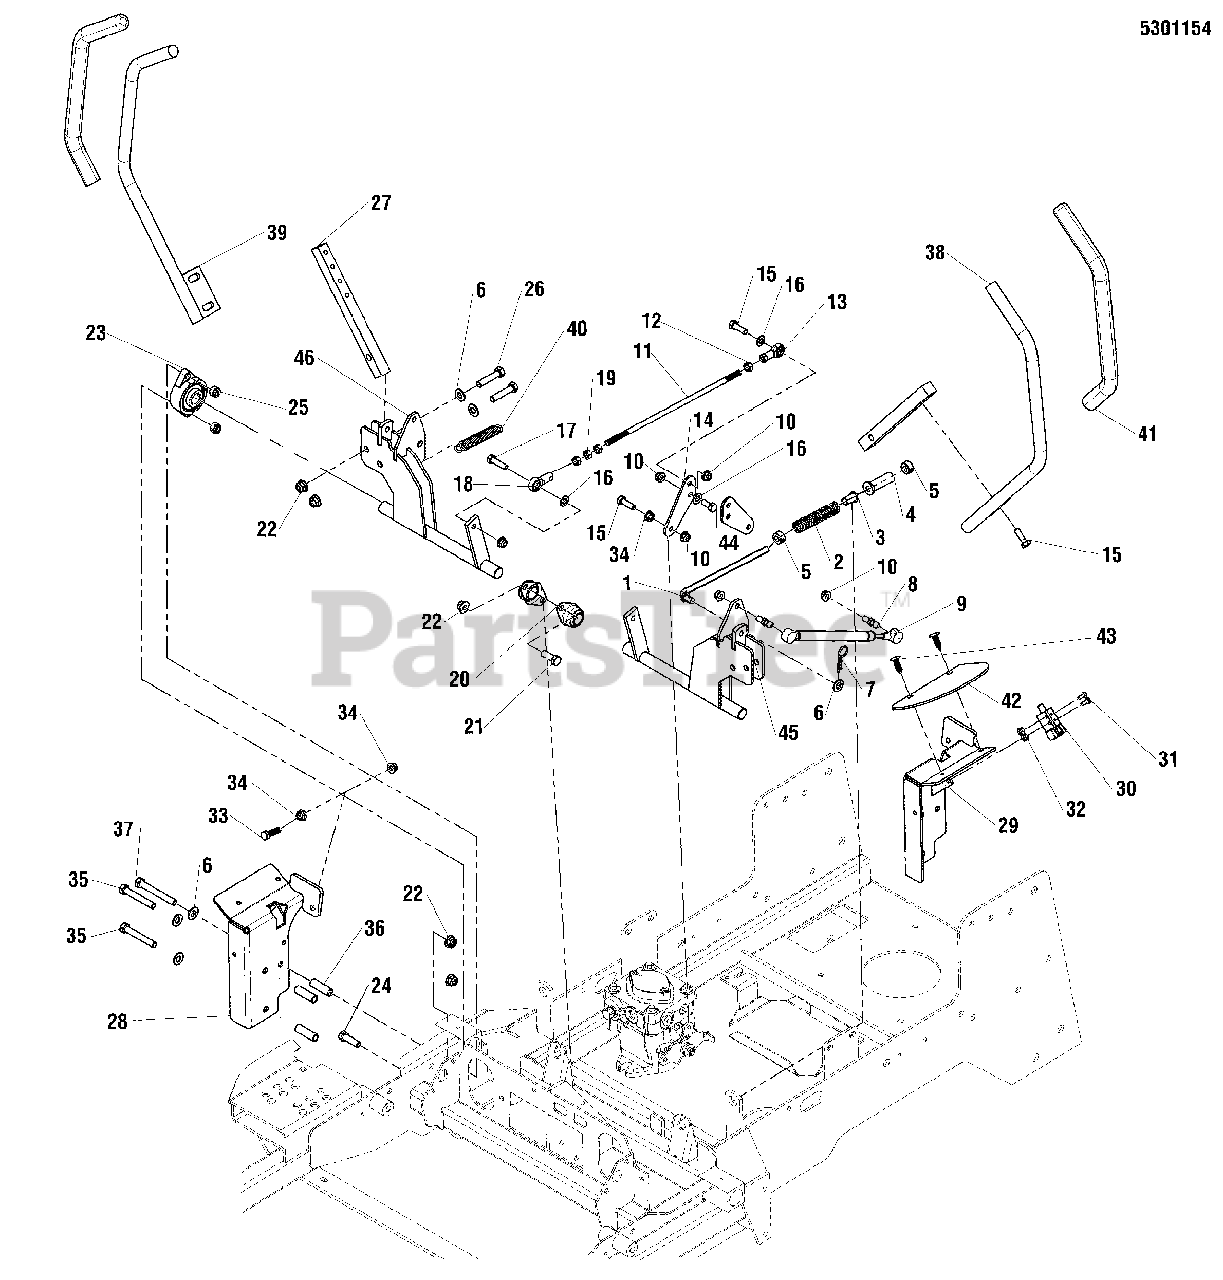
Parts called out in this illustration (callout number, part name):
1	ROD, NEUTRAL RETURN, CZ
2	SPRING, REVERSE RETURN
3	BUSHING, FLANGE 3/8ID X 7/8 LONG
4	FLANGED BUSHING, 3/8IDX.63ODX.8125FL
5	COLLAR, 3/8" SET
6	WASHER, Flat, 3/8
7	PIN, HAIR, .0915 X 1-7/8
8	BALL STUD, 5/16 X .50, (# PC-477-2)
9	DAMPENER, CONTROL, #(P6709/P3610)
10	NUT, Ny Lock Flange, 5/16-18
11	ROD, HYDRO LINKAGE
12	NUT, Hex, 5/16-24, LH
13	BALL JOINT 5/16-24 LH FEMALE STAMPED STL
14	PLATE, PUMP SUPPORT - BLK
15	CAPSCREW, Hex Head, Flange Whiz Lock, 5/16-18 x 3/4
16	WASHER, 5/16
17	CAPSCREW, Hex Head, 5/16-18 X 1-1/4
18	BALL JOINT 5/16-24 RH FEMALE STAMPED STL
19	NUT, Hex, 5/16-24
20	BEARING, Flange, Bronze, 3/4"
21	CAPSCREW, Hex Head, 3/8-16 x 1
22	NUT, 3/8-16, Hex Flange Nylock
23	BEARING, FLANGE
24	CAPSCREW, Hex Head, 3/8-16 x 1-1/4
25	NUT, Hex, Nylon Lock, 3/8-16
26	CAPSCREW, Hex Head, 3/8-16 X 1-3/4
27	MOUNT, CONTROL ARM - BLK
28	WELD, NEUTRAL LOCK - RH - IS500Z - BLK
29	WELD, NEUTRAL LOCK - LH - IS500Z - BLK
30	SWITCH, Push Button, N.O . N.C, Double Pole, Grey
31	SCREW, #10-24 X 1/2" ROUND PHILLIPS
32	NUT, Hex, #10-24
33	CAPSCREW, Hex Head, 5/16-18 X 1-1/8
34	NUT, 5/16-18, Hex Serrated Flange (Small)
35	BOLT, 3/8-16 X 2-1/2"
36	SPACER, .39 X .63 X 1.50, CZ
37	CAPSCREW, Hex Head, 3/8-16 x 3
38	WELD, HANDLE MOTION CONTROL, LH - BLK
39	WELD, HANDLE MOTION CONTROL, RH - BLK
40	SPRING-EXT, .500 OD X 3.50 LG X .058 WR
41	GRIP, FOAM, 3/4" ID, 16" LONG
42	GUARD, RUBBER MOT CTRS - IS500Z
43	PUSH RIVET (TREE TYPE), BLACK
44	CAPSCREW, Hex Head, 5/16-18 x 3/4
45	SHAFT MTN CNTRL LH
46	SHAFT MTN CNTRL RH
